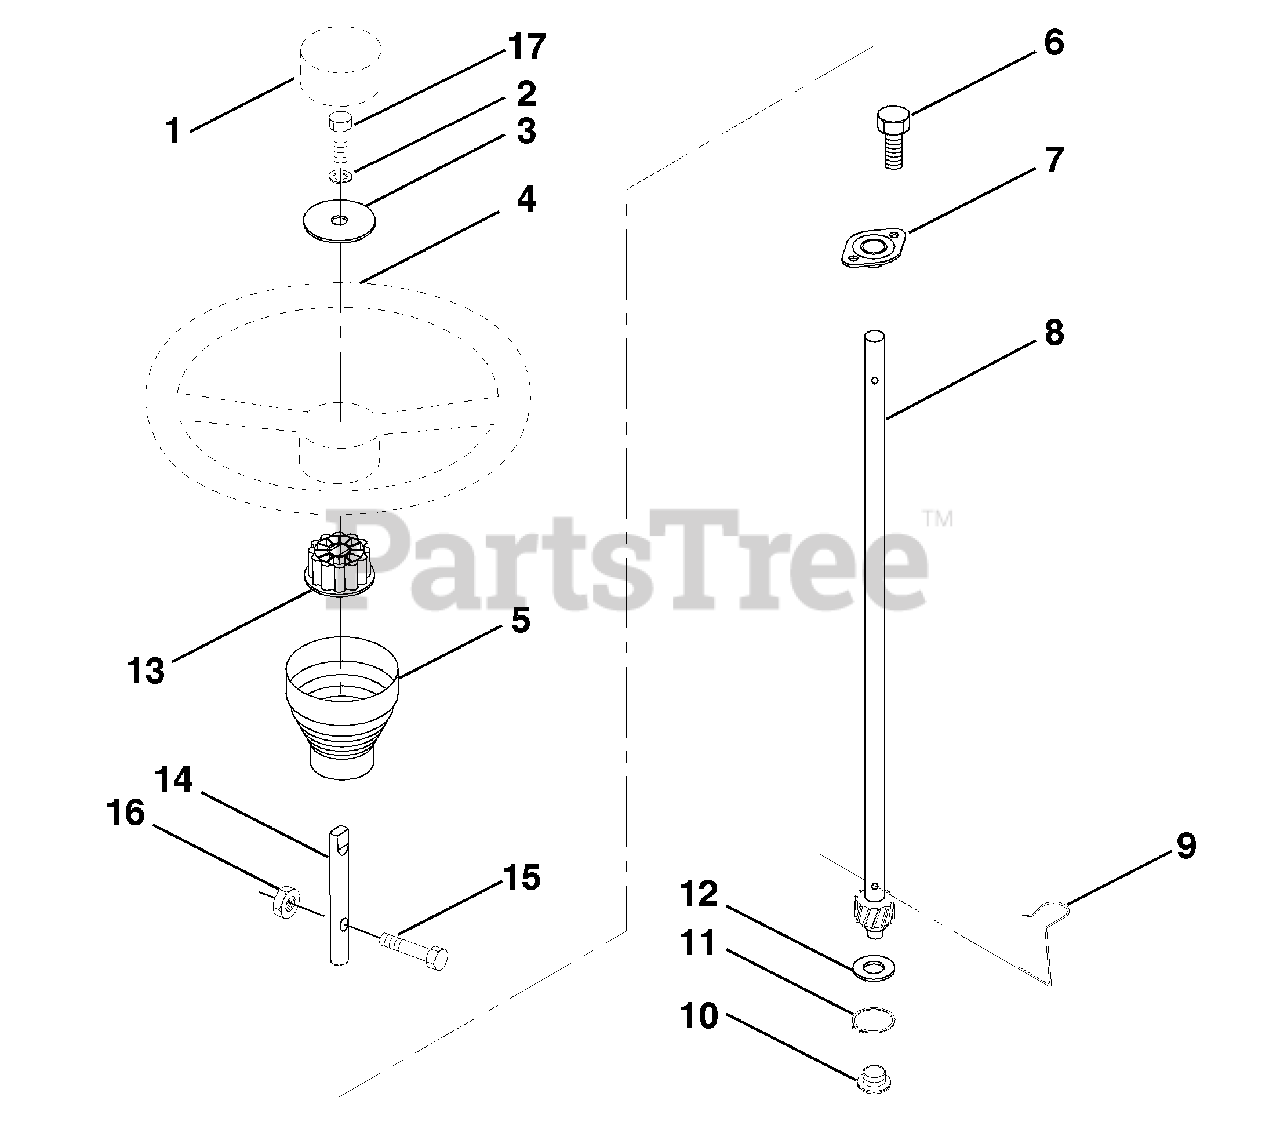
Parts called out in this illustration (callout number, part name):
1	Insert, Wheel, Steering
2	Washer, Lock hvy HLCL SPR 3/8
3	Washer 12/32 x 2-3/8 x 8 Ga.
4	Wheel, Steering
5	Sleeve, Steering
6	Screw, TT #10-32.5. 3/8 flange
7	Bushing, Steering
8	Shaft, Steering
9	Clip, Steering
10	Bushing, Lower, Steering
11	Ring, Retaining
12	Washer 21/32 x 1 x 16 Ga.
13	Adaptor, Wheel, Steering
14	Extension shaft steering
15	Bolt Fin Hex 5/16-18 UNC x 1-1/4
16	Nut Lock Hex W/Ins. 5/16-18 UNC
17	Bolt fin Hex 3/8-16 UNC x 1. Gr. 5
